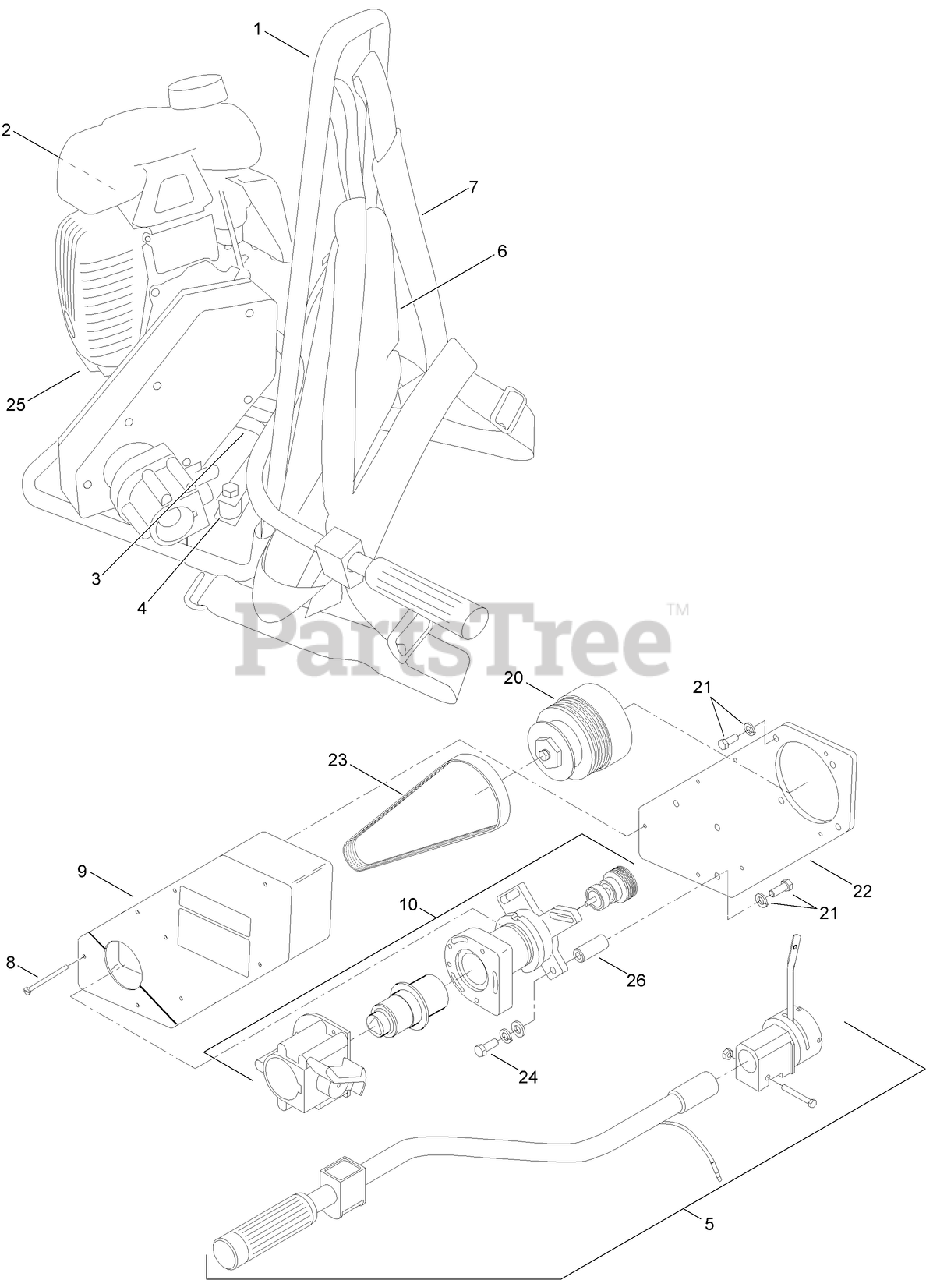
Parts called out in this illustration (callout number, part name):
1	FRAME ASM
2	STARTER-RECOIL
3	SPIDER ASM
4	MOUNT-SHOCK, RUBBER
5	ROTARY THROTTLE ASM
6	BACKPACK PAD WITH VELCRO STRAP ASM
7	BACKPACK SHOULDER STRAP ASM
8	SCREW AND RETAINING WASHER ASM
9	GUARD-BELT
10	DRIVE BLOCK ASM
20	CLUTCH ASM
21	SCREW-PLATE, TRANSMISSION
22	PLATE-MOUNT, TRANSMISSION
23	V-BELT, 6 GROOVE
24	SCREW-HOUSING, BEARING BLOCK
25	LH ENGINE BASE ASM
26	Spacer
